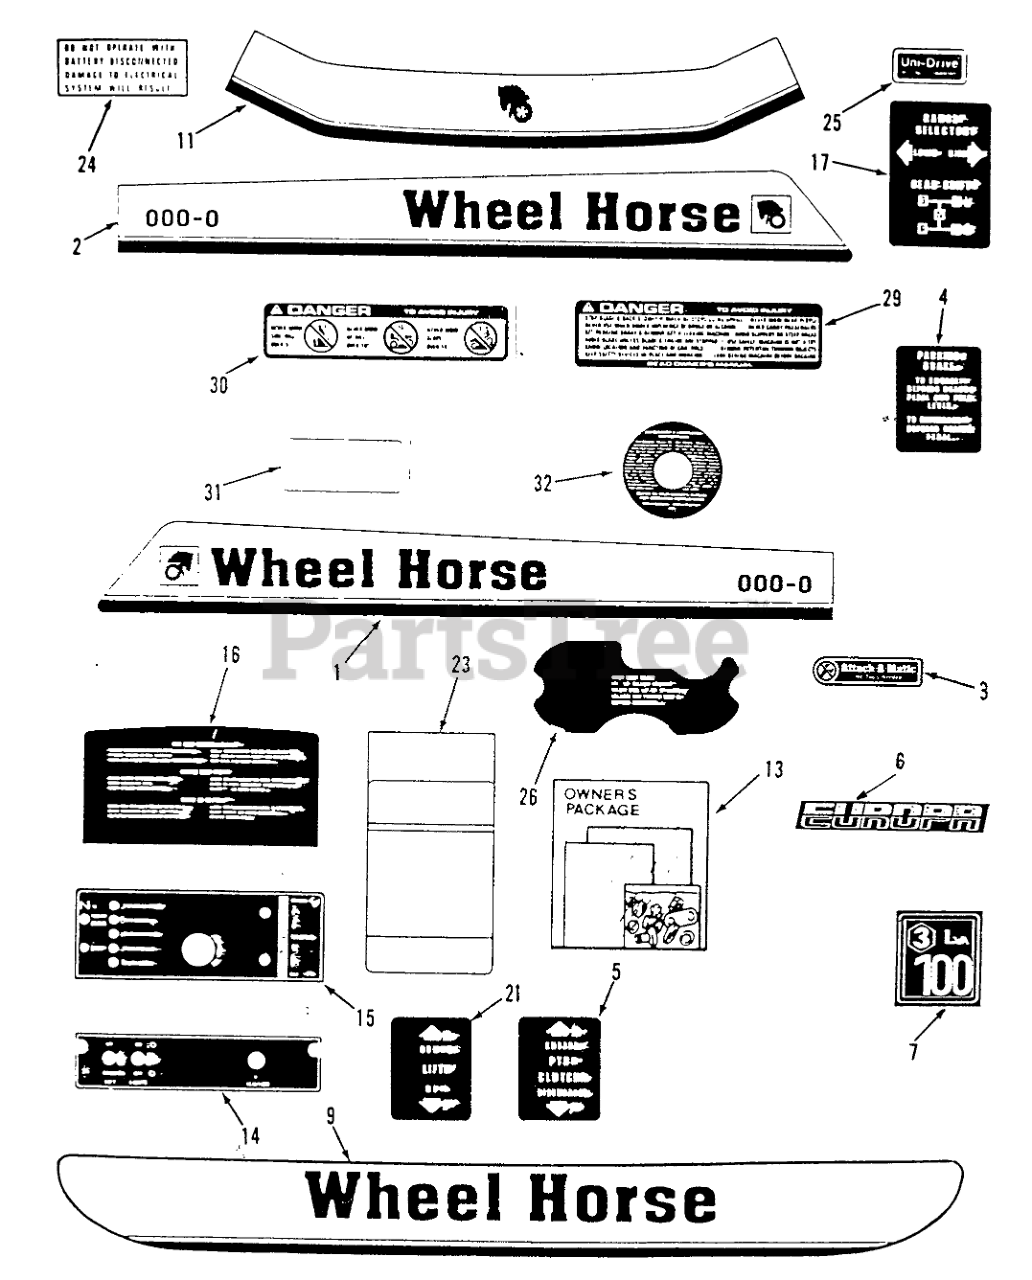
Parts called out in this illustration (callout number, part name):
1	Decal-Hood RH 312
2	DECAL-HOOD 312-8 L H
3	Decal-Attac-O-Matic
4	DECAL-PARKING, BRAKE
5	DECAL PTO CLUTCH
6	DECAL-EUROPA
7	DECAL-EUROPE
9	DECAL-FENDER
11	DECAL-FRONT HOOD
14	DECAL BACK PLATE
15	Decal-Lower Dash 416
16	DECAL-REAR HOOD
17	DECAL-SHIFT PATTERN
21	DECAL-LIFT
23	MAINTENANCE-DECAL
24	DECAL ELECT SYSTEM
25	Decal-Unidrive
26	DECAL-SEAT LIFTER
29	Decal-Danger
30	Decal-Danger
31	DECAL-OVERLAY
32	Decal-Air Cleaner
